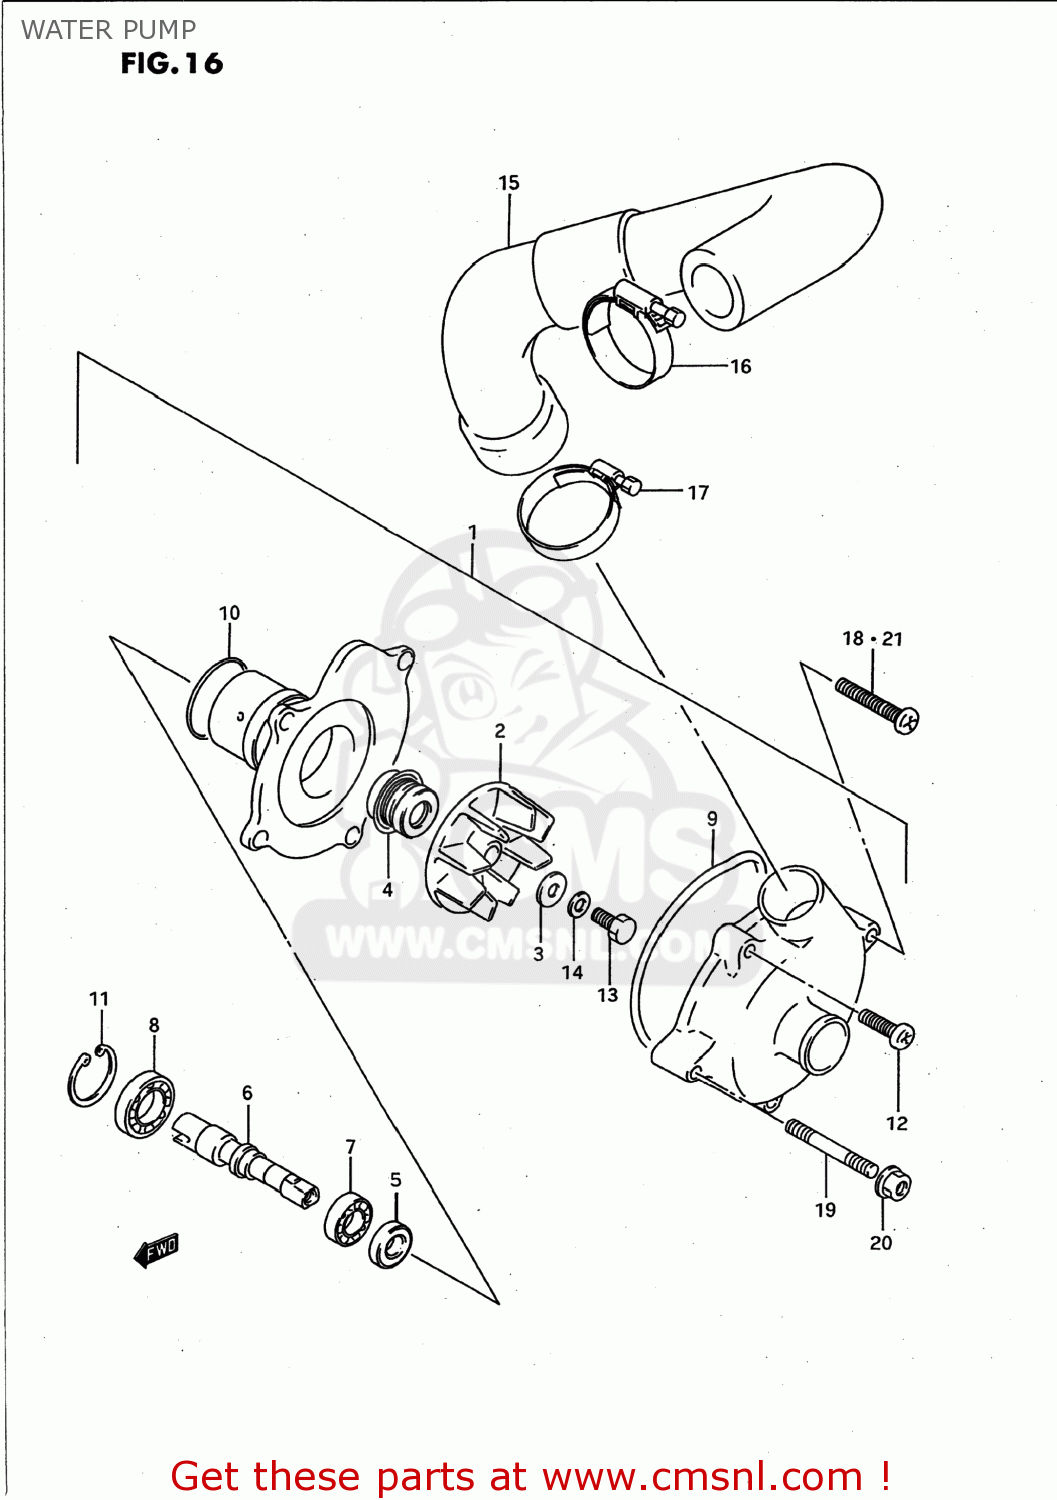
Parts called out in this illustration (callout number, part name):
1	PUMP ASSY,WATER
2	IMPELLER
3	GASKET(6X15X2.2) (NAS)
4	SEAL,MECHANICAL
5	OILSEAL
6	SHAFT
7	BEARING
8	BEARING(12X28X8)
9	O RING
10	O RING,WATER PUMP HOLDER
11	CIRCLIP
12	SCREW
13	BOLT(6X13)
14	WASHER
15	HOSE,WATER PUMP,OUTLET
16	CLAMP
17	CLAMP
18	SCREW
19	BOLT,STUD
20	NUT
21	SCREW
